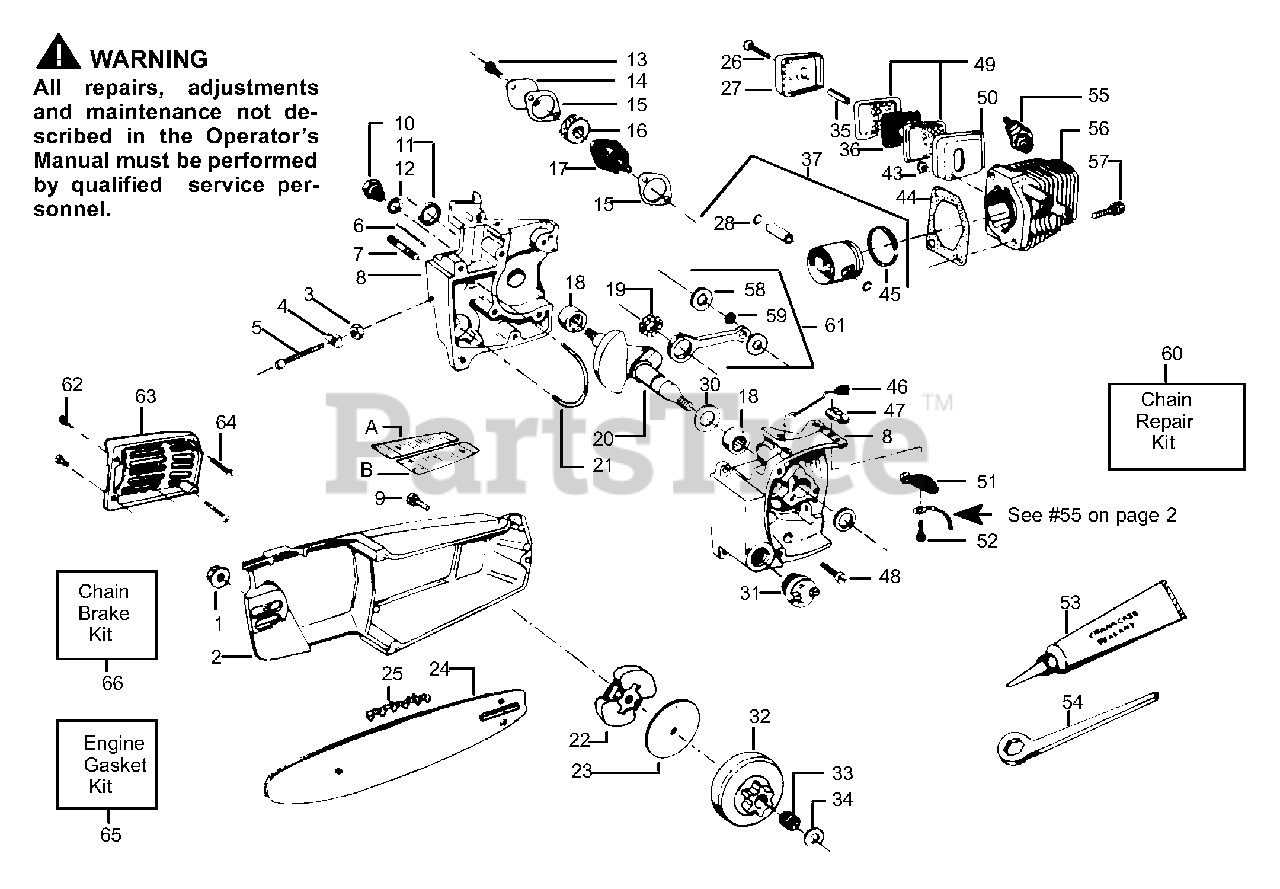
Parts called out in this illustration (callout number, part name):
1	Bar Mounting Nut
2	Bar Clamp
3	Lock Nut
4	Bar Adjust Pin
6	Oil Tank Vent Pin
7	Bar Mounting Stud
8	Crankcase Ass'y
10	Check Valve Kit-
11	Crankshaft Seal
12	Check Valve Gasket
14	Metering Body Cover
15	Metering Body Gasket
16	Oil Filter
17	Metering Body Ass'y.
18	Crankshaft Bearing
19	Roller Bearing
20	Crankshaft
21	Oil Discharge Line
22	Clutch Ass'y. Kit
23	Clutch Washer Kit
24	Guide Bar 14"
24	Guide Bar 16
25	Chain 14" (P101S-52)
25	Chain 16" (P101S-56)
27	Muffler Cover
28	Piston Pin Retainer
30	Thrust Washer
31	Oil Cap Ass'y. T1
31	Oil Cap Ass'y. T2
32	Clutch Drum
33	Clutch Bearing
34	Clutch Spacer (Inside)
36	Spark Arrestor Screen
37	Piston Kit Model 200 & 205
37	Piston Kit Model 225 & 235
44	Cylinder Gasket
45	Piston Ring Model 200 & 205
45	Piston Ring Model 225 & 235
46	Switch Knob Model 200, 205 & 225
46	Switch Knob Model 235
47	Ramp Switch
49	Muffler Baffle
50	Muffler Body
51	Switch Clamp
53	Crankcase Sealant
54	Bar Adjusting Tool
55	Spark Plug CJ-8
56	Cylinder Model 200 & 205
56	Cylinder Model 225 & 235
59	Bearing Rod
60	Chain Repair Kit
61	Connecting Rod Ass'y. Kit
63	Muffler Shield
65	Engine Gasket Kit
66	Chain Brake Kit
A	Instructions Decal Right Hand
B	Instructions Decal Left Hand
